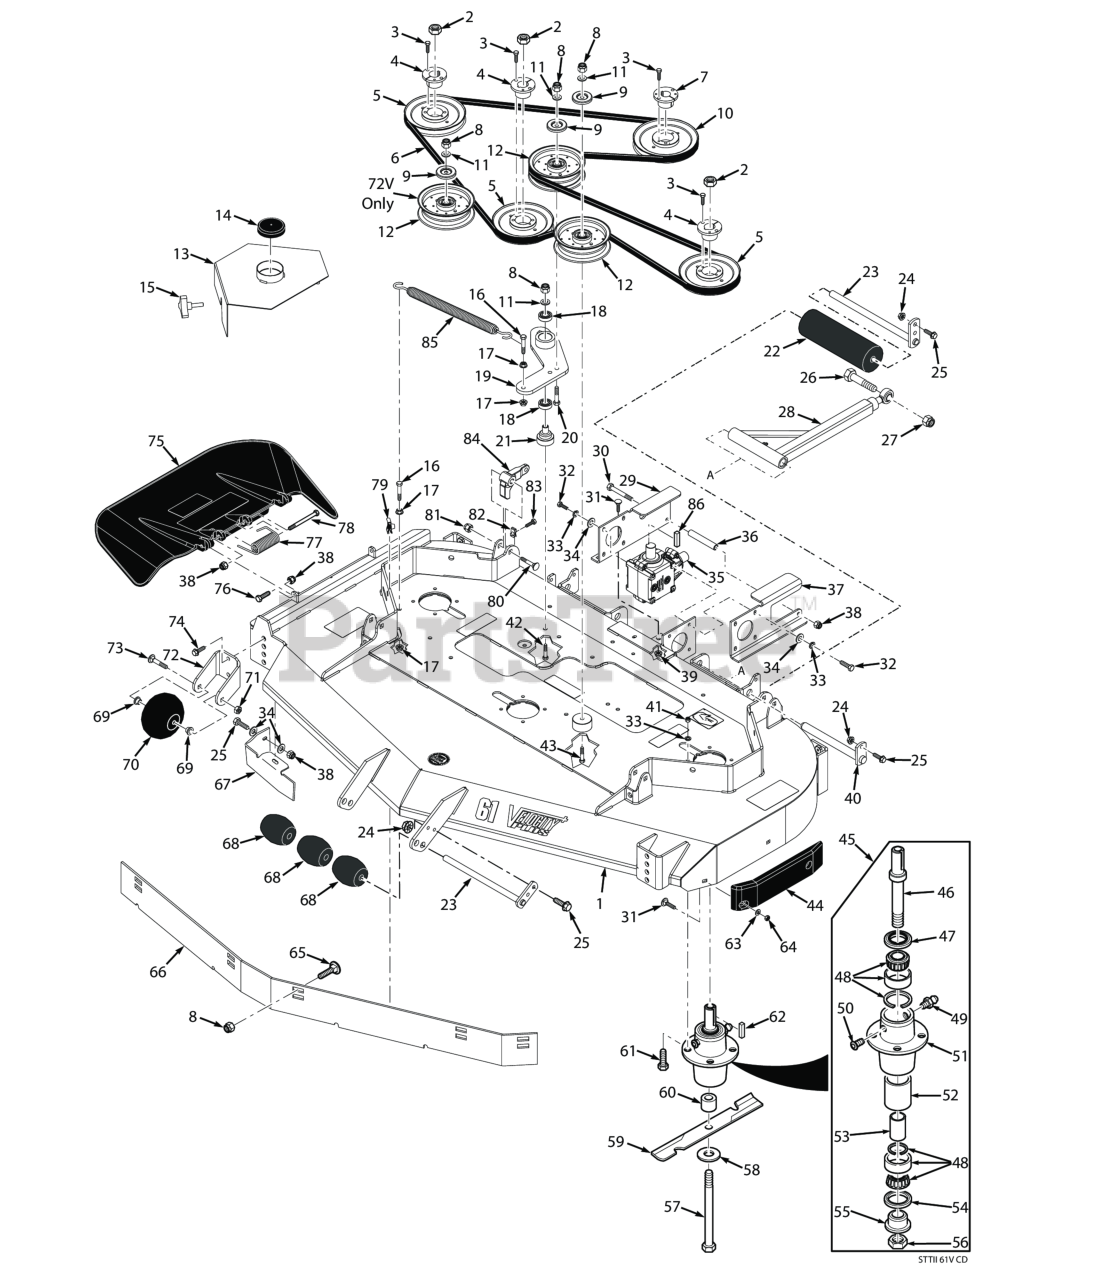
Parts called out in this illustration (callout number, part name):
1	Cutter Deck w/Decals - 61V
2	Hex Locknut, Elastic Stop, 3/8-16
3	Bolt, Hex Head 1/4-20 x 1" Grade 8 Black
4	Hub, Tapered 1-1/8" Bore
5	Pulley, 6.35 O.D. (Diesel Engine)
6	Belt, Cutter Deck Drive - Kubota
7	TAPERED HUB, 1.00" BORE
8	HEX NUT, ELASTIC STOP LOCK, 3/8-16
9	Quick Pin, 5/16" Dia.
10	Pulley, 6.75 O.D. - 61"
11	Flatwasher, 3/8 (.391 x .938 x .105 HD) Grade 8
12	Idler Pulley, Belt Clutch
13	Belt Cover, 61V (incl. #14)
15	Knob, w/stud 3/8-16 x 1-1/4"
16	Bolt, Hex Head 3/8-16 x 1-1/2" Grade 8 Black
17	NUT, 3/8-16 SERRATED FLANGE HEX HEAD
18	BEARINGS, BALL, NEUTRAL RETURN
19	Idler Arm, Cutter Deck
20	Capscrew, Hex Head 3/8-16 x 2.75"
21	Pivot, Idler - Short
22	Wheel, Anti-ScalpRelief Fitting, Tapered Spindle
23	Shaft Weldment, Guide Roller
24	Nut, Flange Head Elastic Stop 5/16-18
25	Bolt, Heax Head 5/16-18 x 1" (48V / 52V)
26	BOLT, HEX HEAD 5/8-11 X 4-1/2"
27	HEX LOCKNUT, ELASTIC STOP, 5/8-11
28	Push Arm (Includes 64,60,62)
29	Mounting Plate
30	Bolt, 5/16-18 x 4-3/4" Hex Head
31	Bolt, 5/16-18 x .75 RHSN Carriage
32	Bolt, Heax Head 5/16-18 x 1" (48V / 52V)
33	Lockwasher, 5/16 (.317 x .586 x .078) Helical Spring
34	Flatwasher, 5/16-.375 x .875 x .083 (35BV & 37BV-EFI)
35	Gearbox Assembly, Deck Drive
36	Spacer, Gearbox Mount
37	Mounting Plate
38	HEX NUT, ELASTIC STOP LOCK, 5/16-18
39	Nut, Serrated Flange 5/16-18 (Right Front Engine Mounting, Briggs and Kohler Only)
40	Shaft Weldment, Pusharm
41	Lock Nut, 5/16-18 Elastic Stop Grade 8
42	Bolt, Hex Head 3/8-16 x 3" - 52"
43	Capscrew, Hex Head 3/8-16 x 3-3/4"
44	Pad, Deck Wear
45	Cutter Spindle Assembly
46	Spindle Shaft, Tapered Brng
47	SEAL, 2.00 O.D. X 1.50 BORE
48	Tapered Bearing Set (Two Bearings W/Race)
49	GREASE FITTING, STR. 1/4-28 SELF TAP.
50	RELIEF FITTING, TAPERED BEARING SPINDLE
51	Housing, Spindle
52	Spacer, Outside, Cutter Spindle
53	SLEEVE, CUTTER SPINDLE
54	Seal, 2.00" O.D. x 1.625" Bore
55	SPINDLE BUSHING, BOTTOM
56	Nut , Spec ial 1 -1/ 1 6 - 1 8
57	BOLT, HEX HEAD, 5/8-11 X 9-1/2 GR.5
58	Flatwasher, 5/8-.688 x 1-3/4 x .134 HD
59	Cutter Blade, 21" Standard
60	Spacer, Spindle Bottom
61	Bolt, Hex Head 5/16-18 x 1-3/4" Grade 8
62	Key, 1/4 x 1/4 x 2.0"
63	Flatwasher, 5/16-.344 x .688 x .065 (48V / 52V)
64	Nut, Center Lock, 5/16-18(32)
65	Carriage Bolt, 3/8-16 x 1.0"
66	Baffle Custom-Cut, 61V (7-Position)
67	Turbo Baffle, Bolt On
68	Wheel, Anti-Scalp
69	Bushing, .376" I.D. Oilite
70	Bolt, Carriage 3/8-16 x 4"
71	Bolt, Hex Head 3/8-16 x 1" Ser. Flg.
72	Bracket, Anti-Scalp Wheel
73	Bolt, Hex Head 3/8-16 x 3-1/2"
74	Capscrew, 3/8-16 x 1.0" Serrated Flange Hex Hd
75	Discharge Chute Advantage - Large
76	Bolt, Hex Head 5/16-18 x 1-1/2" - Front
77	Spring, Discharge Chute
78	Bolt, 5/16-18 x 4-3/4" Hex Head
79	U-Nut, 3/8-16
80	Bolt, Carriage 7/16-14 x 2-1/4"
81	HEX LOCKNUT, ELASTIC STOP, 7/16-14
82	U-Nut, 3/8-16 (short)
83	Bolt, Hex Head 3/8-16 x 2" Special Lock
84	Lever, Deck Level
85	Spring, Cutter Deck
86	Key, 1/4 x 1/4 x 1.25" Pulley Mtg.
